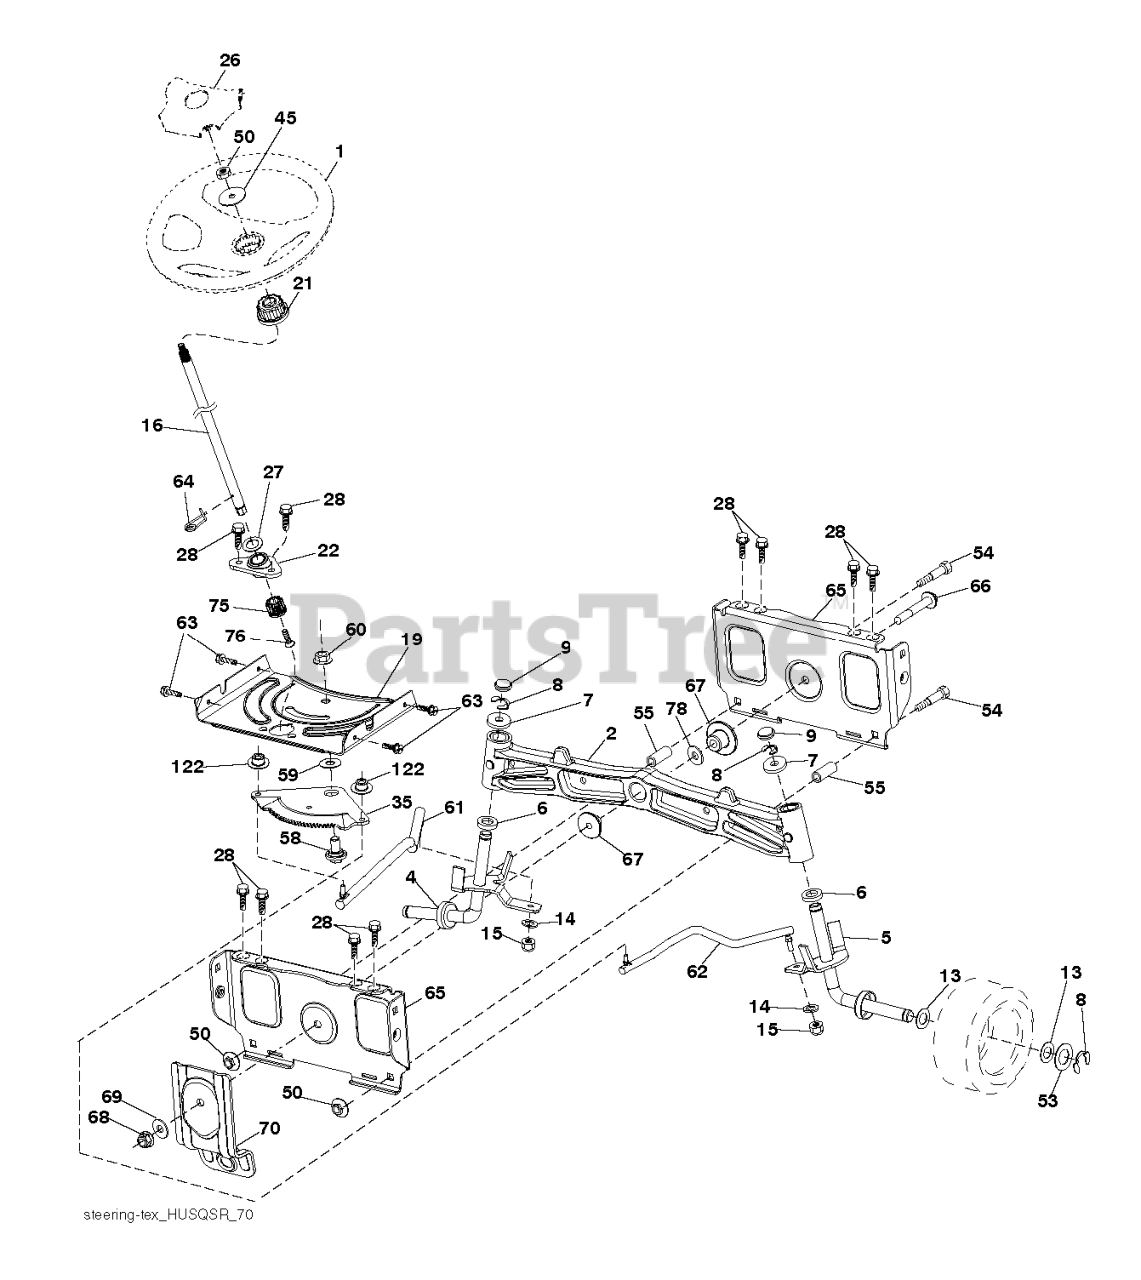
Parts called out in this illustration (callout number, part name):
1	WHEEL.STEER.HUSQ.SR.498.OVMLD
2	AXLE.CAST.IRON
4	SPINDLE.ASM.LH
5	SPINDLE.ASM.RH
6	THRUST WASHER
9	CAP.SPINDLE.BLACK
14	SLW 3/8 STD
15	NUT CROWNLOCK 3/8-24
16	SHAFT.STEER.2HIGH.SPLND.PLATED
19	PLATE.STEER.DDL.NLT/NG
21	ADAPTER.WHEEL.STEER.SPLND.ALUM
22	BEARING.SHAFT.STEER.LOWER.625
26	INSERT.CAP.WHL.STRG.HUSQ.PREM
27	WASHER LT
28	SCREW, 3/8-16X3/4
35	GEAR.SECTOR.PLATE.DDL.
45	WASHER.3/8ID.2-3/8OD.12GA.PLTD
50	NUT LOCK FLG 3/8-16 UNC
53	WASHER.HARDENED
55	SPACER.BRACE.AXLE
58	BOLT.SHOULDER.SECTOR.P
59	WASHER.THURST.SECTOR.S
60	NUT FLANGE LOCK 5/8-11
61	DRAGLINK.LH.BALLSTUD.D
62	DRAGLINK.RH.BALLSTUD.D
63	SCREW
64	RETAINER.CLIP.SPRING.S
65	BRACE.AXLE.FRONT.NLT/N
66	BOLT HEX FGHD 7/16-14 X 3 SERR
67	BUSHING.PM.FRONT AXLE
68	NUT.LOCK.FLANGE.7/16
69	WASHER.1.5X.505X.118
70	BRACKET.FRT.DECK.SUSP.RR.MT431
75	PINION.ZINC PLATED
76	SCREW HEAD SOCKET LRVB
78	THRUST WASHER
122	CAP.GEAR.SECTOR.TEX
